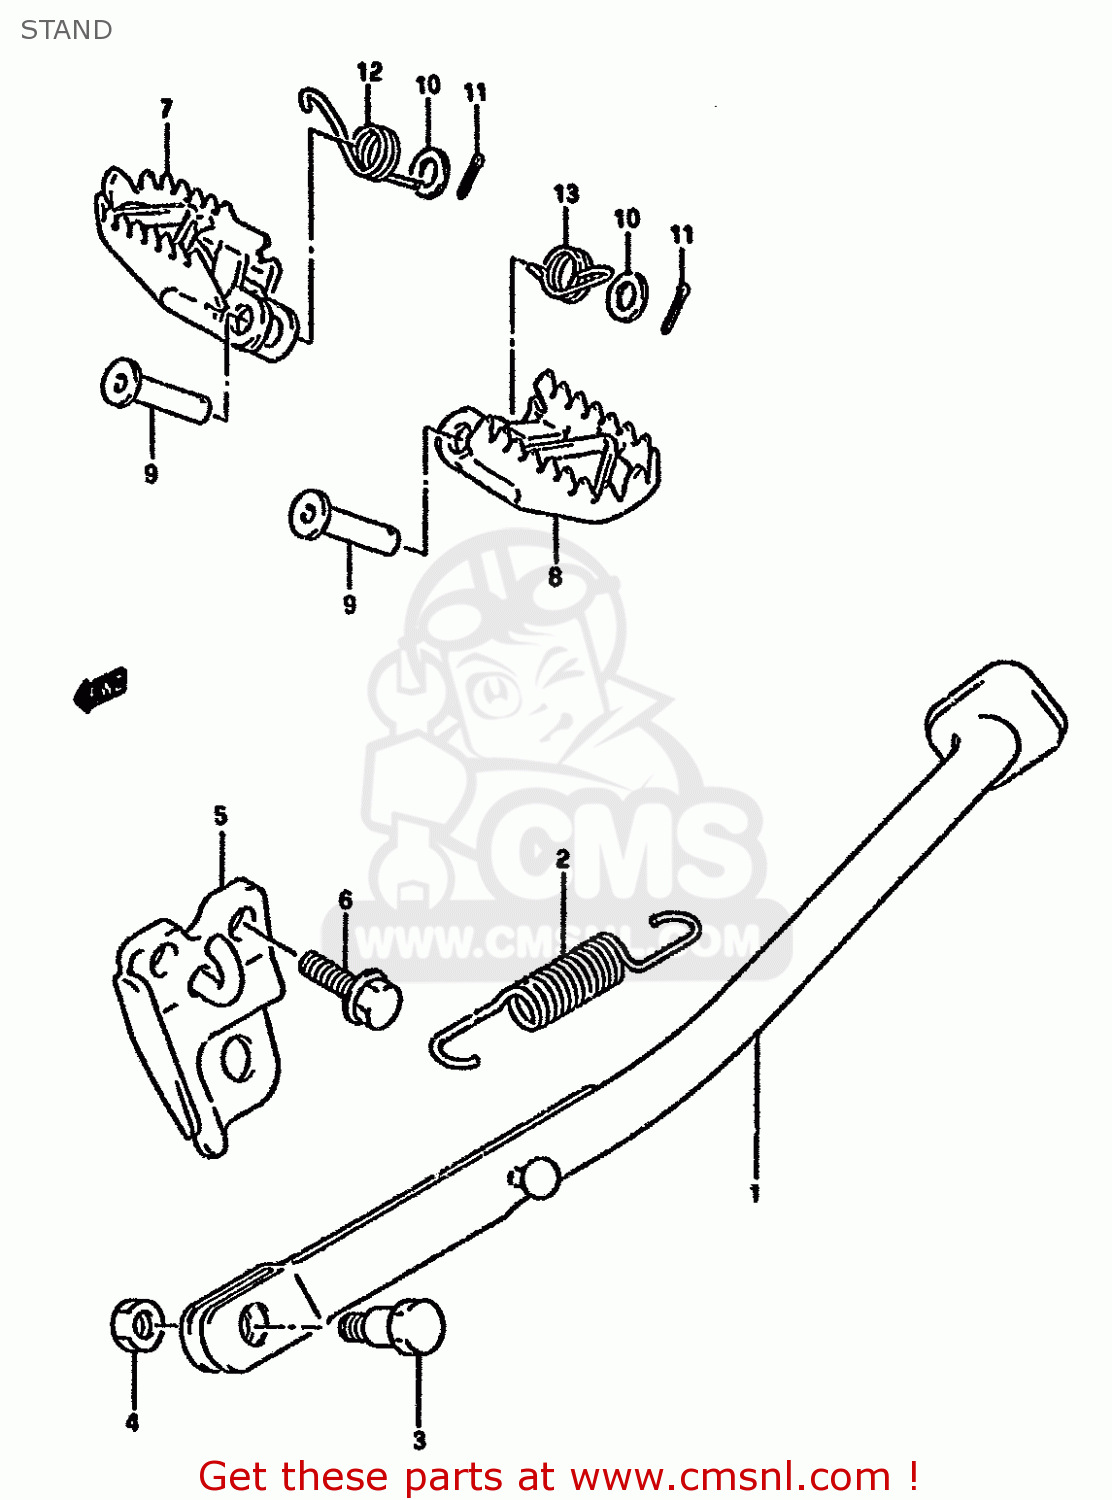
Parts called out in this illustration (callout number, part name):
1	STAND,PROP(SILVER)
2	SPRING
3	BOLT(10X30)
4	NUT
5	BRACKET,PROP STAND
6	BOLT(10X25)
7	FOOTREST,R
8	FOOTREST,L
9	PIN(10X41.5)
10	WASHER
11	PIN 25X20
12	SPRING
13	SPRING
